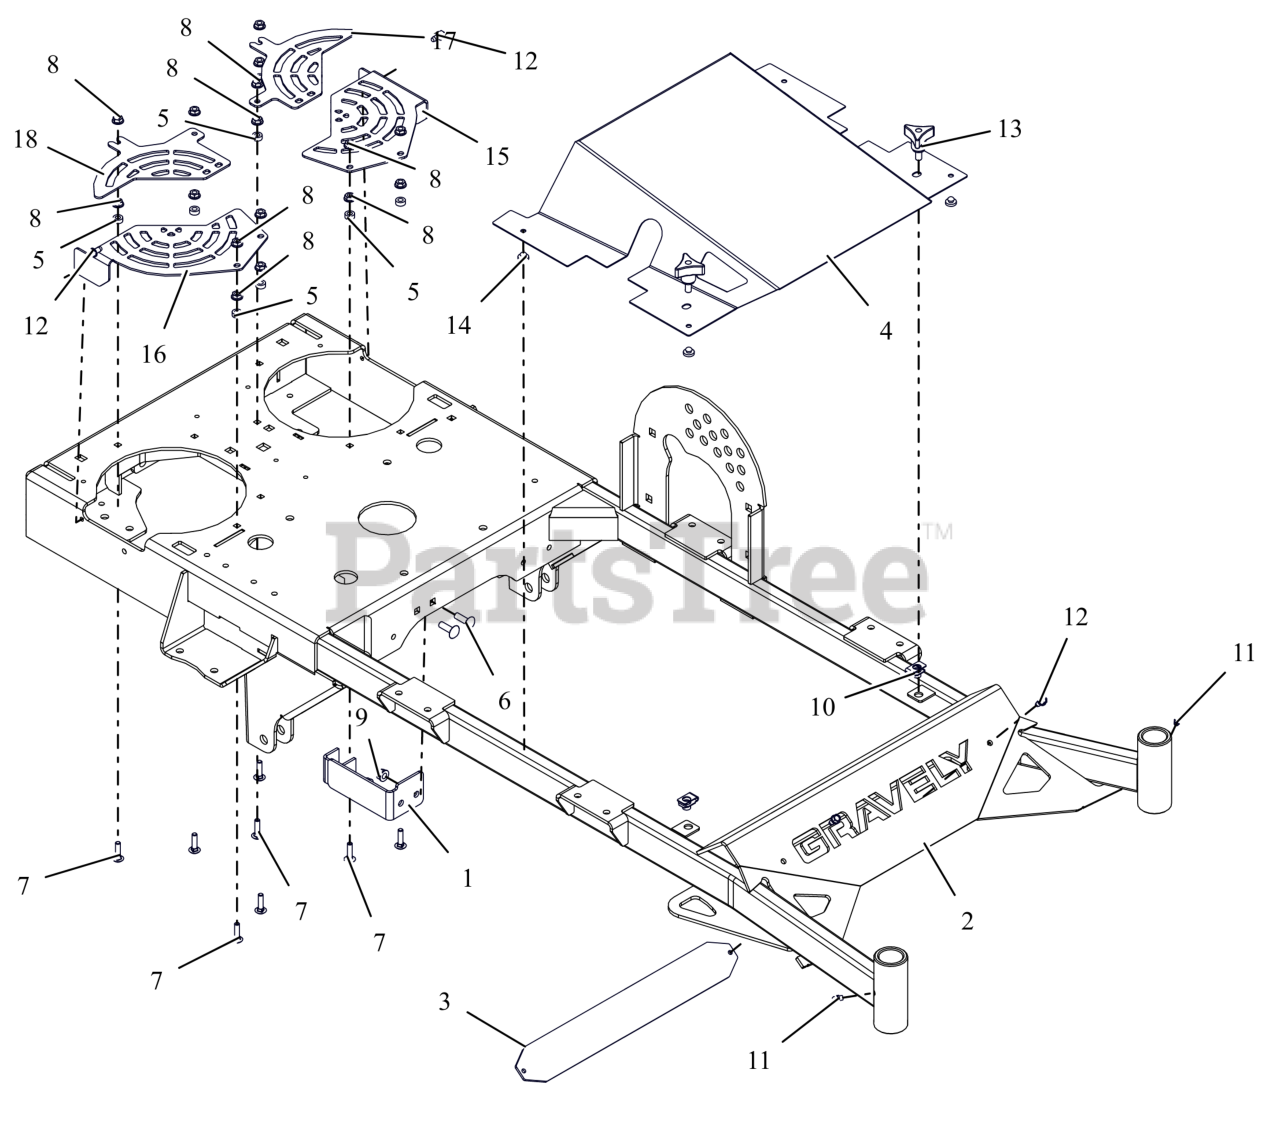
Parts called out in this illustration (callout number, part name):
1	WLDMT, CLUTCH STOP
2	WLDMT, FRAME 36" PRO WLK (RED)
3	BACKER, NAMEPLATE
4	SHIELD, FRONT 36" PRO-WALK (RED)
5	BSHG-SLV .265X.500X.219
6	BLT,RHSSN .31-18X1.00 G5 ZCC
7	BLT, RHSN .25-20X1.00 G5 ZCC
8	NUT-LK-CTR-FLG .25-20 ZC120
9	NUT,LK-CTR-FLG .31-18 GF ZCC
10	NUT-CLIP RETAINER 5/16-18X.56
11	FTG-LUBE .25-28X.256 SST
12	SCR-TAP .25-20X.50 HWH ZCC
13	KNOB,WING STUD 5/16-18 X .75
14	BUMPER GROMMET
15	GUARD, LH FAN - 36" (RED)
16	GUARD, RH FAN - 36" (RED)
17	GUARD, LH FAN - 36" (RED)
18	GUARD, RH FAN - 36" (RED)
